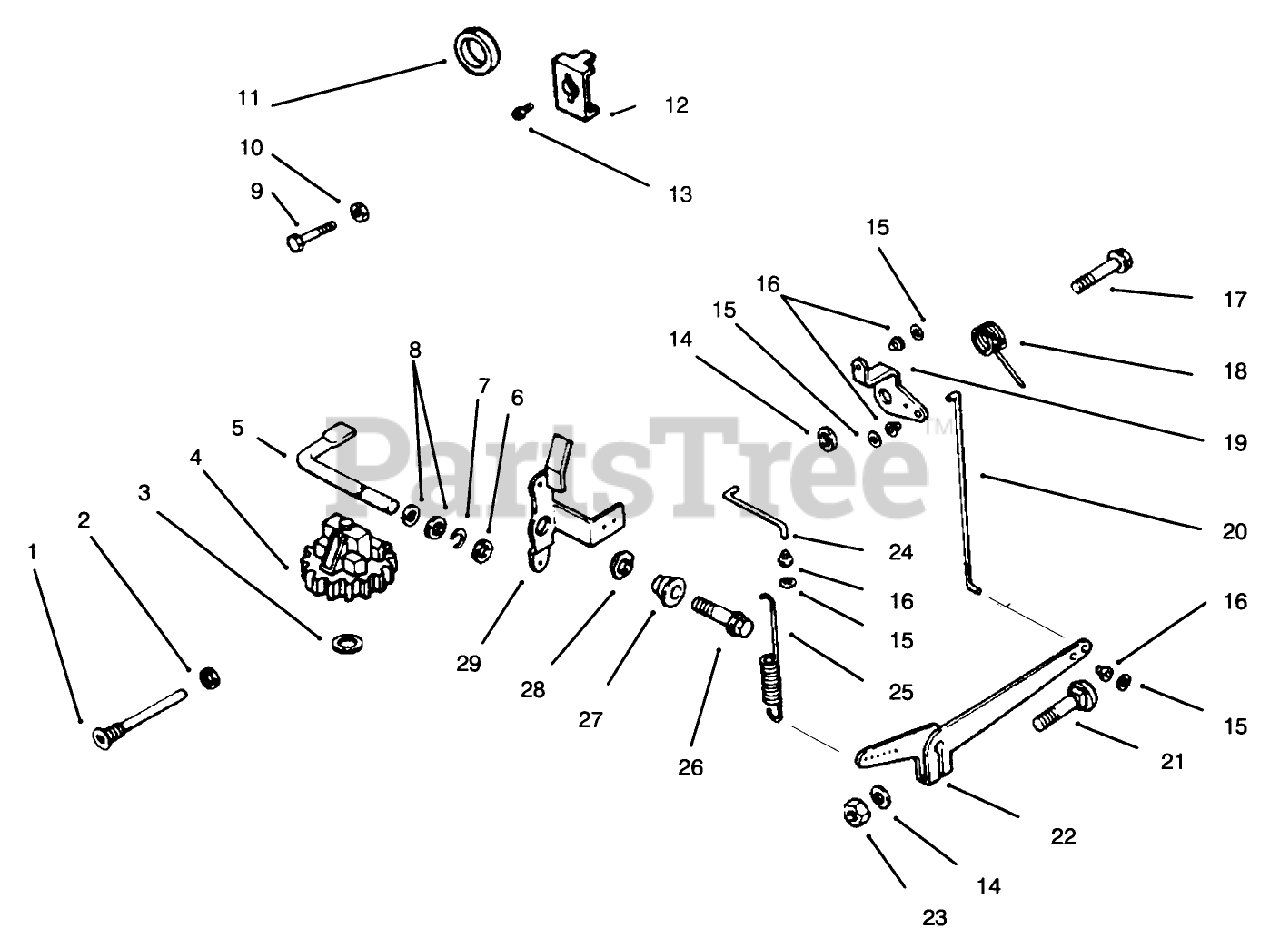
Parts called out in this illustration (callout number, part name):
1	Pin-GovemorStop
2	Washer
3	Washer
4	Governor Gear
5	Shaft-Governor Cross
6	Washer
7	Retainer-Governor
8	Washer
9	Screw-Hex. Hd.
10	Nut
11	Spacer
12	Clamp
13	Screw
14	Washer
15	Ring
16	Bushing-Linkage
17	Screw-Hex Wash. Hd.
18	Spring-Torsion
19	Lever-Throttle
20	Linkage-Governor
21	Bolt
22	Arm-Governor
23	Nut
24	Unkage-Throttle
25	Spring-Governor
26	Screw-Hex. Washer Hd.
27	Bushing-Throttle Control
28	Washer
29	Lever-Speed Control
